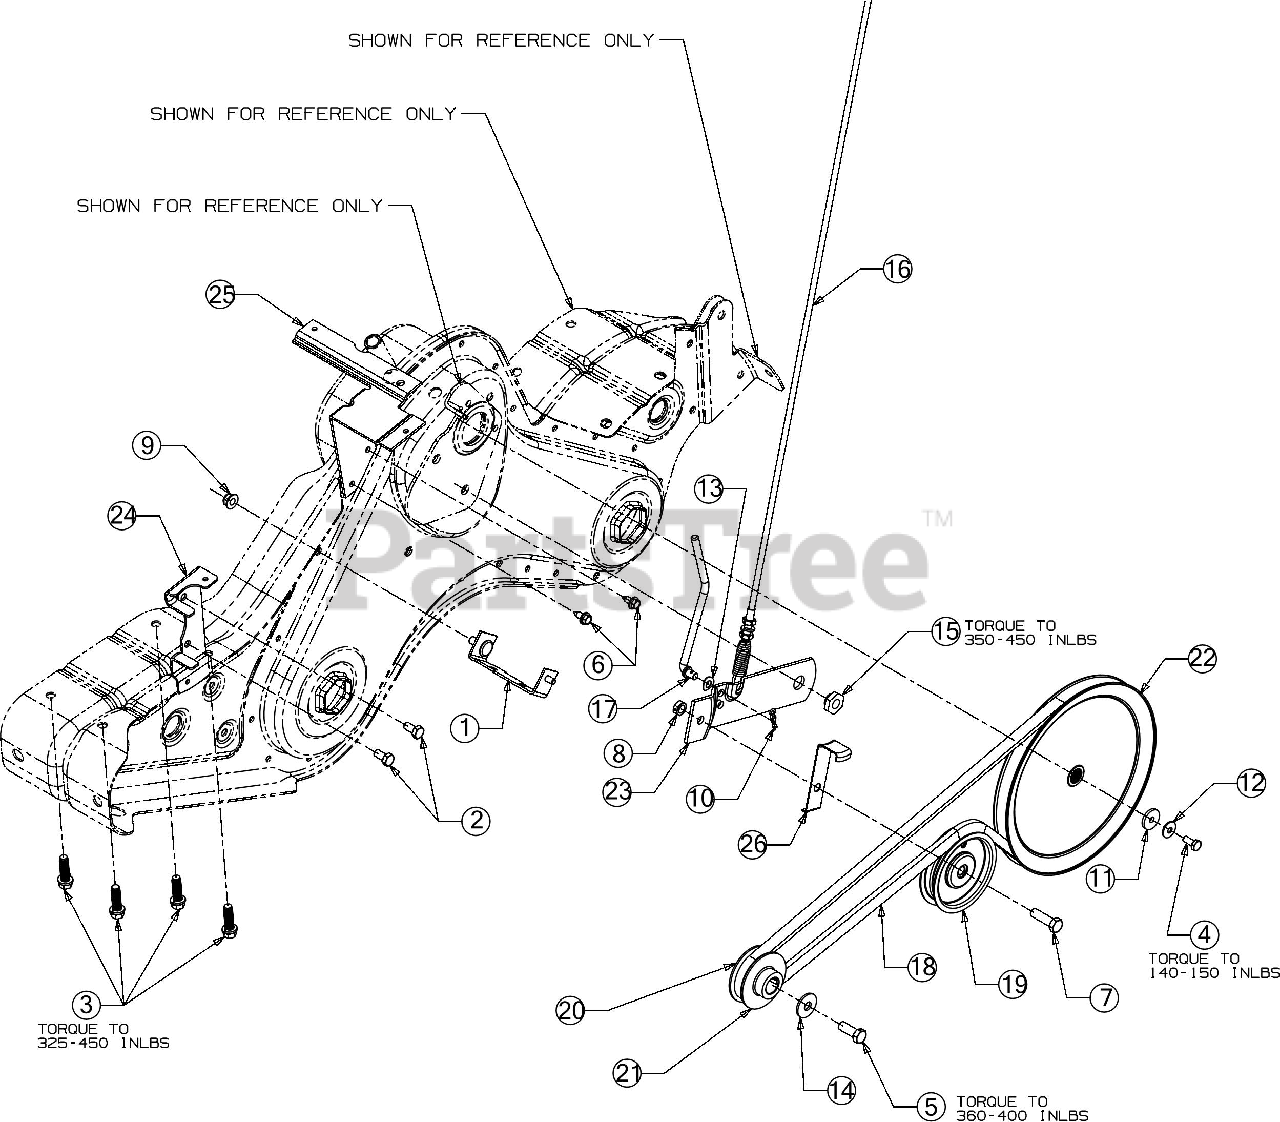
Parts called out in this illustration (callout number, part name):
1	BELT COVER BRACKET ASSEMBLY
1	WELD BOLT 5/16-18 X .875
2	HEX SCREW 5/16-24 X .62
3	SCREW 3/8-16 X 1.250
4	BOLT 1/4-28 X .625 GR8
5	SCREW 3/8-24 X 1.00 GR8
6	SCREW 1/4-20X.625
7	SCREW 3/8-16 X 1.25 GR5
8	JAM LOCK NUT
9	FLANGE LOCK NUT 5/16-18
10	COTTER PIN .072 DIA
11	FLAT WASHER
12	SPRING WASHER BELL
13	SPRING WASHER .317 X .625 X .020
14	BELL WASHER
15	SHOULDER NUT
16	CLUTCH CABLE
17	IDLER PULLEY ROD
18	BELT 1/2 X 58.16
19	IDLER PULLEY
20	ENGINE PULLEY INNER HALF
21	ENGINE PULLEY OUTER HALF
22	INPUT PULLEY
23	IDLER BRACKET
24	BELT KEEPER BRACKET
25	SHIFT COVER BRACKET
26	IDLER BELT KEEPER
